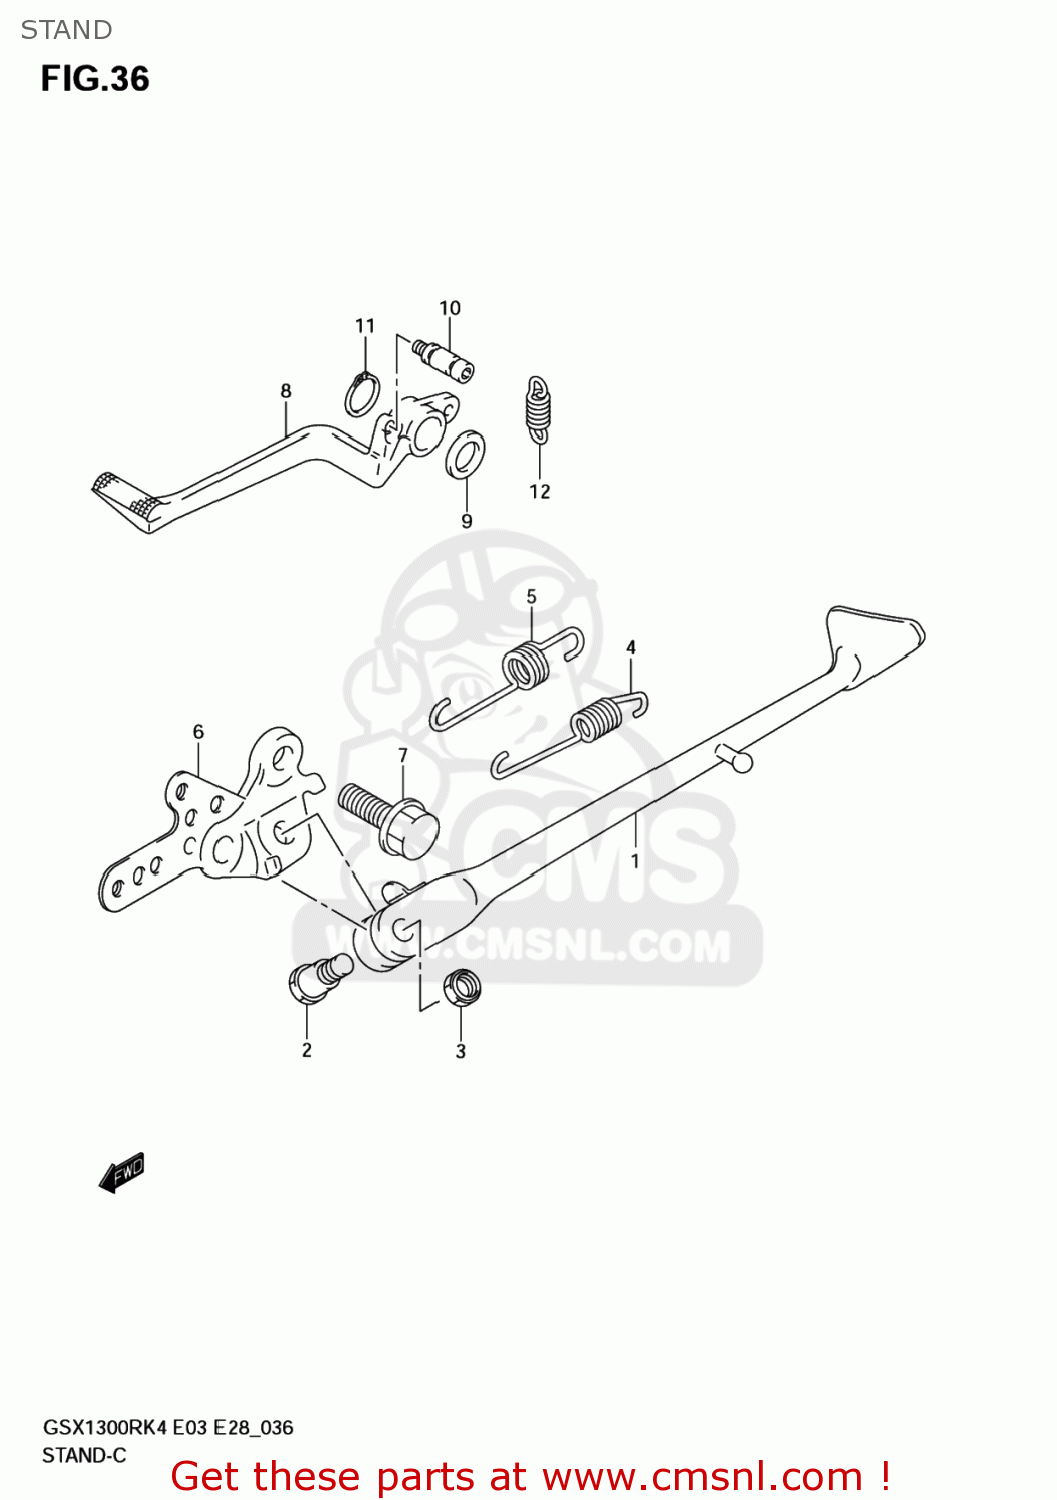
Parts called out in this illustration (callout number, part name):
1	STAND,PROP
2	BOLT(10X21)
3	NUT
4	SPRING
5	SPRING
6	BRACKET COMP,PROP STAND
7	BOLT(12X35)
8	PEDAL,BRAKE
9	WASHER(18X24X1)
10	HOOK,RETURN SPRING
11	CLIP
12	SPRING
